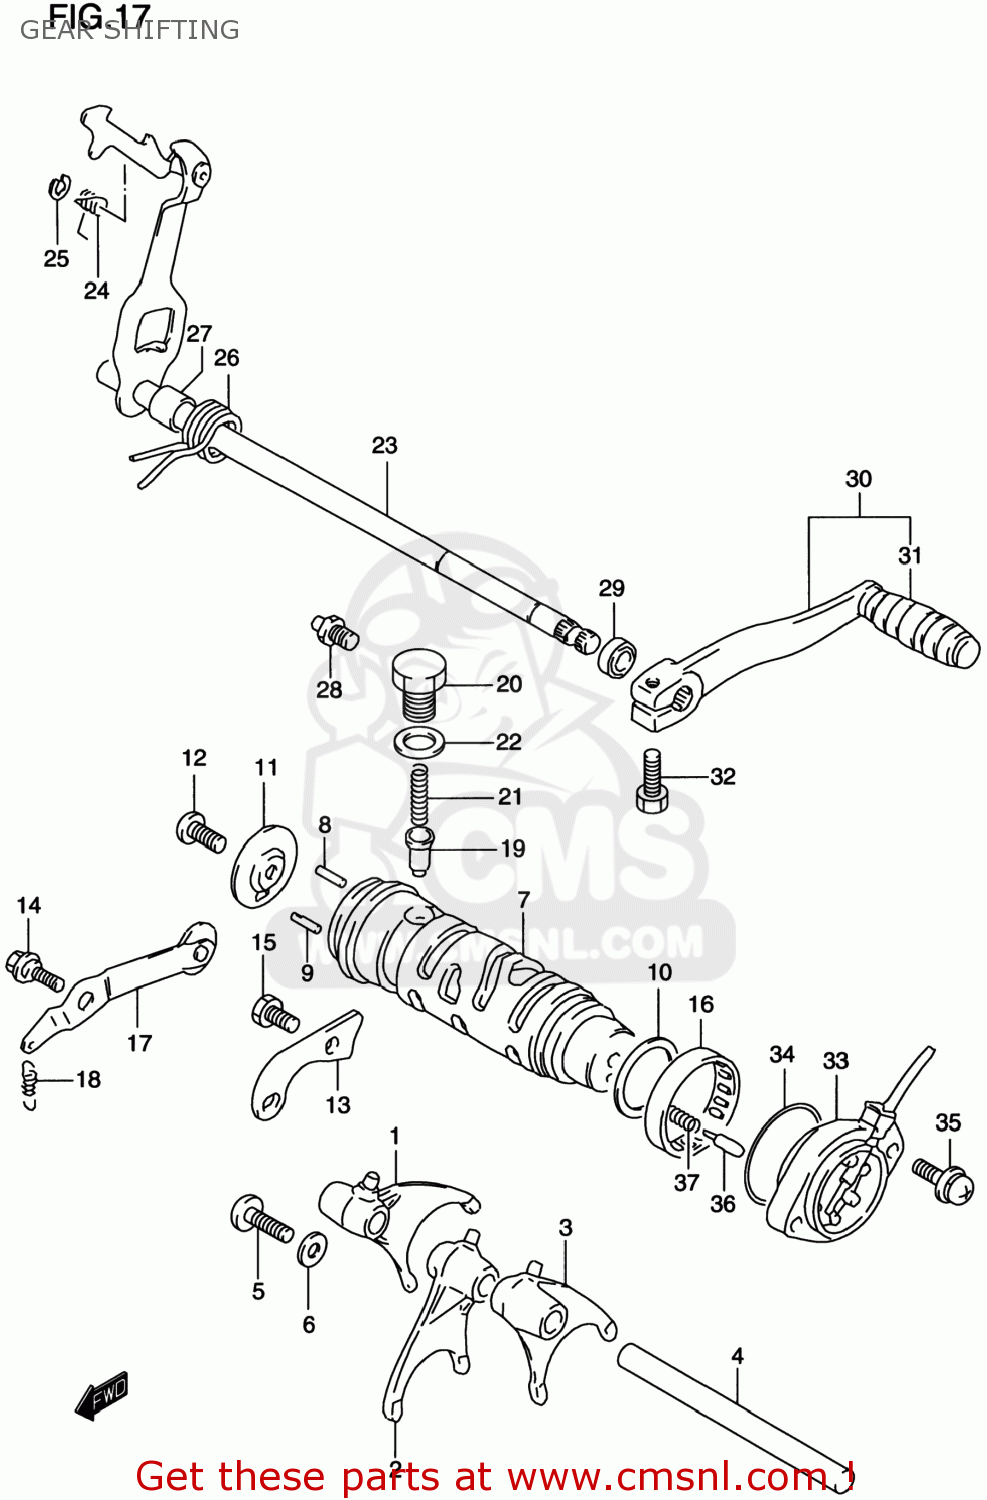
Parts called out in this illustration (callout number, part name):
1	FORK,GEAR SHIFT NO.1
2	FORK,GEAR SHIFT NO.2
3	FORK,GEAR SHIFT NO.2
4	SHAFT,GEAR SHIFT FORK
5	SCREW
6	WASHER
7	CAM,GEAR SHIFT
8	PIN(4X18.5)
9	PIN
10	SHIM(26X32.5X0.3)
11	RETAINER,GEAR SHIFT CAM DR PIN
12	SCREW 6X16
13	GUIDE,GEAR SHIFT CAM
14	BOLT(6X14.6)
15	BOLT
16	BEARING(40X47X12)
17	STOPPER,GEAR SHIFT CAM NO.1
18	SPRING
19	STOPPER,GEAR SHIFT CAM NO.2
20	HOLDER,GEAR SHIFT CAM STOP SPR
21	SPRING
22	GASKET(13.8X18.8X4.8) (NAS)
23	SHAFT,GEAR SHIFT
24	SPRING
25	E-RING
26	SPRING
27	SPACER(12X20X15.3)
28	STOPPER,GEAR SHIFT CAM
29	OIL SEAL
30	LEVER ASSY,GEAR SHIFT
31	RUBBER,GEAR SHIFT PEDAL
32	BOLT
33	BASE ASSY,NEUTRAL SW TERMINAL
34	O-RING (D:2.4 ID:26.2)
35	SCREW
36	PIN(5X15.5)
37	SPRING
